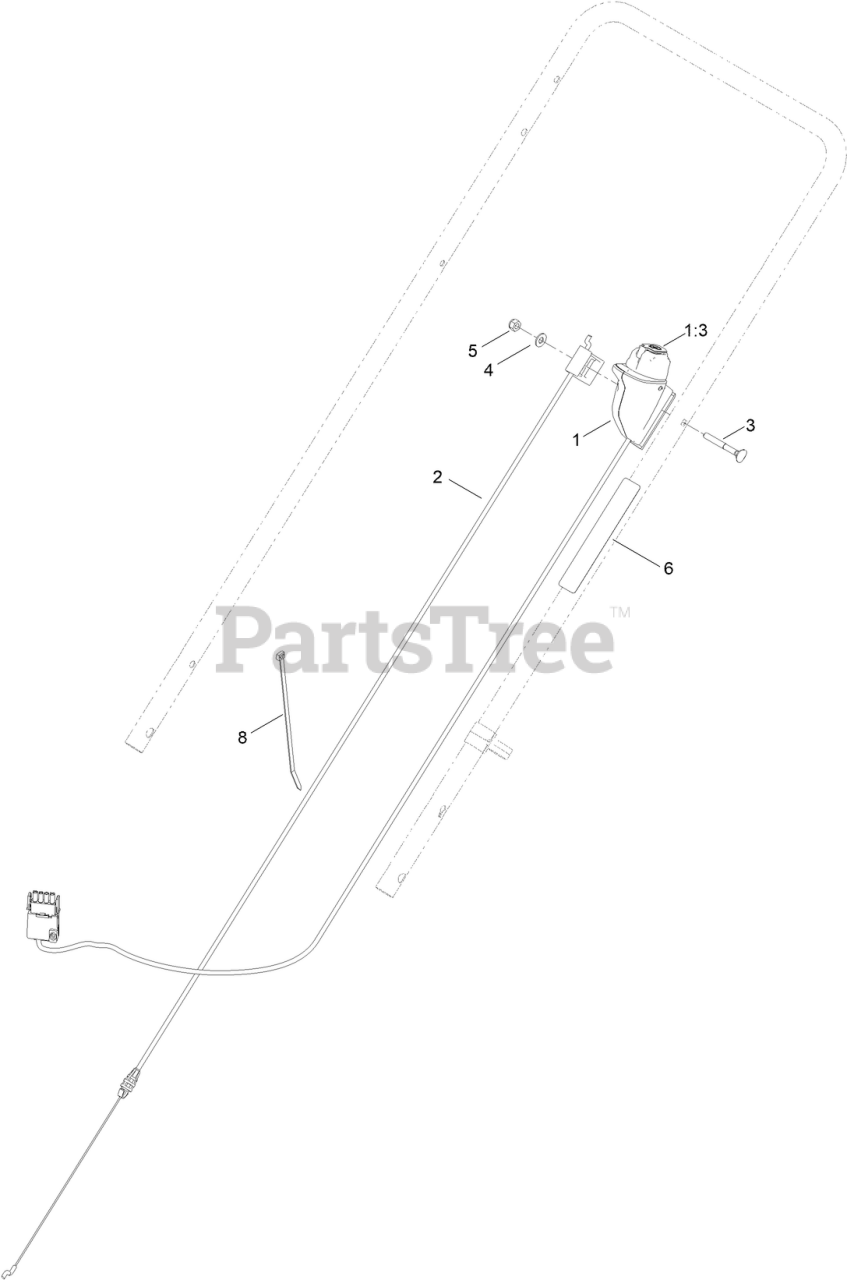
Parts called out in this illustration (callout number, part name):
1	STARTER SWITCH ASM
1:3	STARTER BUTTON SERVICE ASM
2	CABLE - BRAKE
3	SCREW-HANDLE
4	WASHER-FLAT
5	NUT-LOCK, NI
6	DECAL-CONTROLS (60V START)
8	TIE-CABLE
